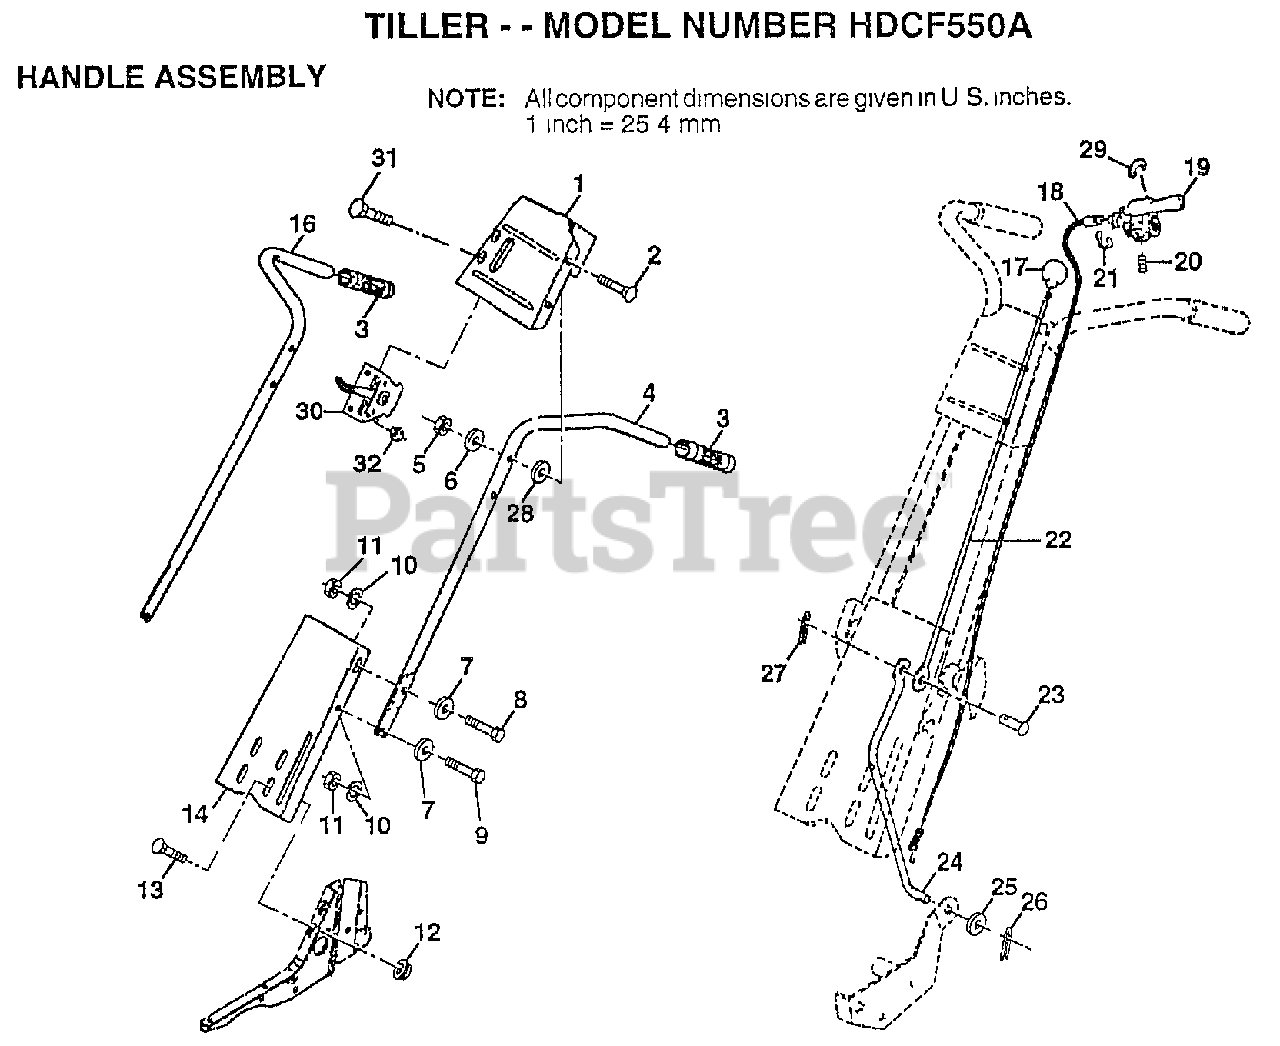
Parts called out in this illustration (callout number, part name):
2	BOLT
4	HANDLE.LH TILLER
6	WASHER
7	WASHER
9	BOLT
10	LOCKWASHER
11	NUT.HEX.5/16-18
12	NUT
13	BOLT
16	"HANDLE-RH,TILLER"
17	KNOB T(3/8 HOLE)
18	CABLE CLUTCH T
19	CABLE CLUTCH T
19	LEVER CONTRL TINE
20	"PIN PIVOT,GROOVED"
21	E-RING
22	ROD REVERSE TI
23	RIVET.RD.HD.DRILL
24	REVERSE ROD TI
25	WASHER
26	COTTER PIN
28	WASHER
29	RETAINER RING
